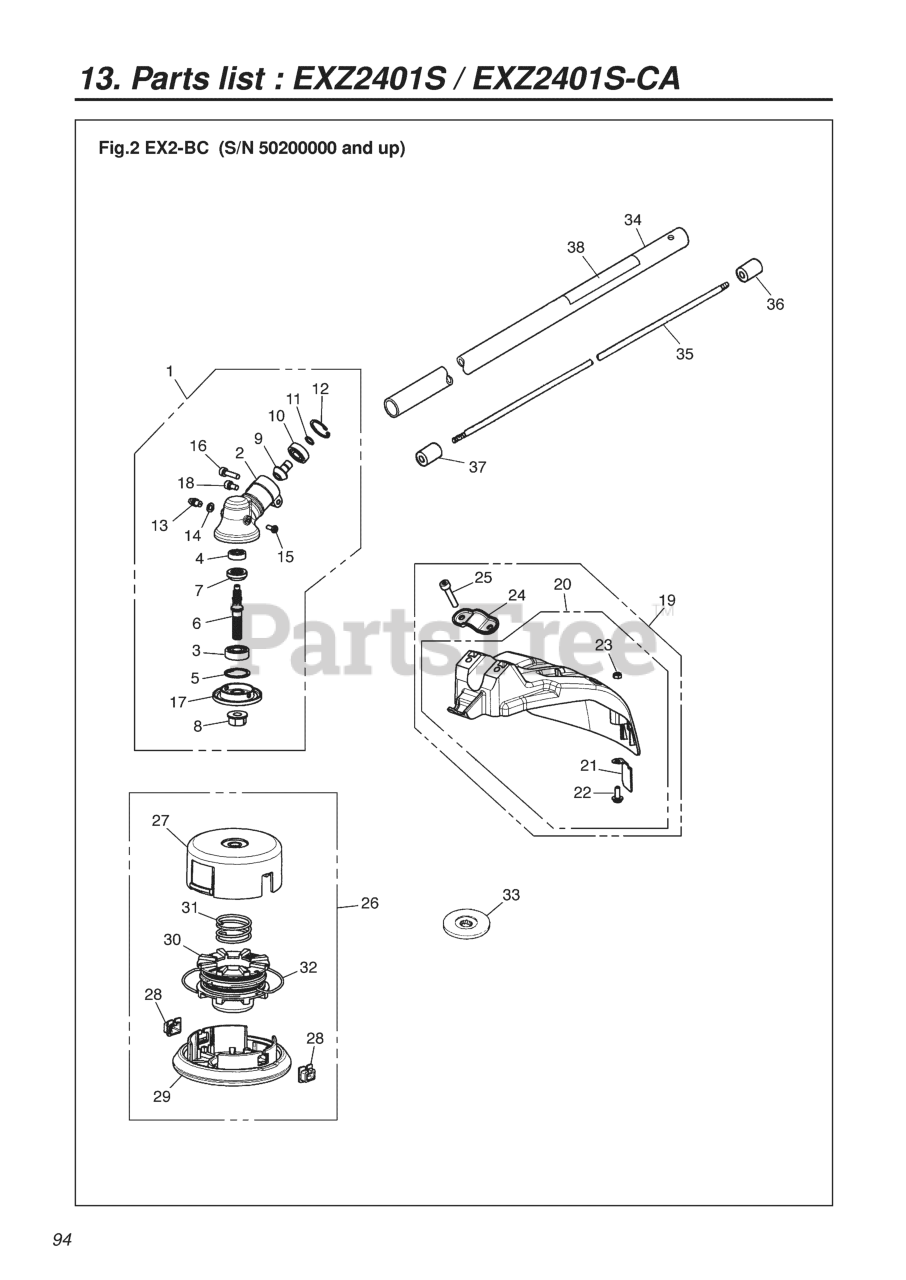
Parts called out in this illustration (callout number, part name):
1	GEARCASE ASSY.
2	GEARCASE
3	BEARING
4	BEARING (RPLS T3300-13521)
5	RING, SNAP, M26 X 1.2
6	SHAFT
7	GEAR
8	NUT
9	PINION
10	BEARING (RPLS T3300-13531)
11	RING, SNAP (RPLS T3300-13330)
12	RING, SNAP, M24 x 1.2
13	FITTING, GREASE
14	WASHER, M6 X .8
16	BOLT (RPLS 2850-14220)
17	HOLDER (A)
18	BOLT
19	GUARD ASSY. (RPLS -24002)
20	GUARD COMP.
21	BLADE (RPLS T3002-24120)
22	SCREW TORX
23	NUT
24	CLAMP (REPLACES 5807-24120)
25	BOLT, TORX
26	TAP HEAD COMP.
27	CASE (REPLACES -15111)
28	EYELET
29	COVER (REPLACES -15131)
30	HOLDER, CORD (REPLACES-15141)
31	SPRING
32	CORD
33	HOLDER (B)
34	PIPE COMPLETE
35	SHAFT
36	JOINT, SHAFT (RPLS -12240)
37	SPACER
38	PLATE, NAME
